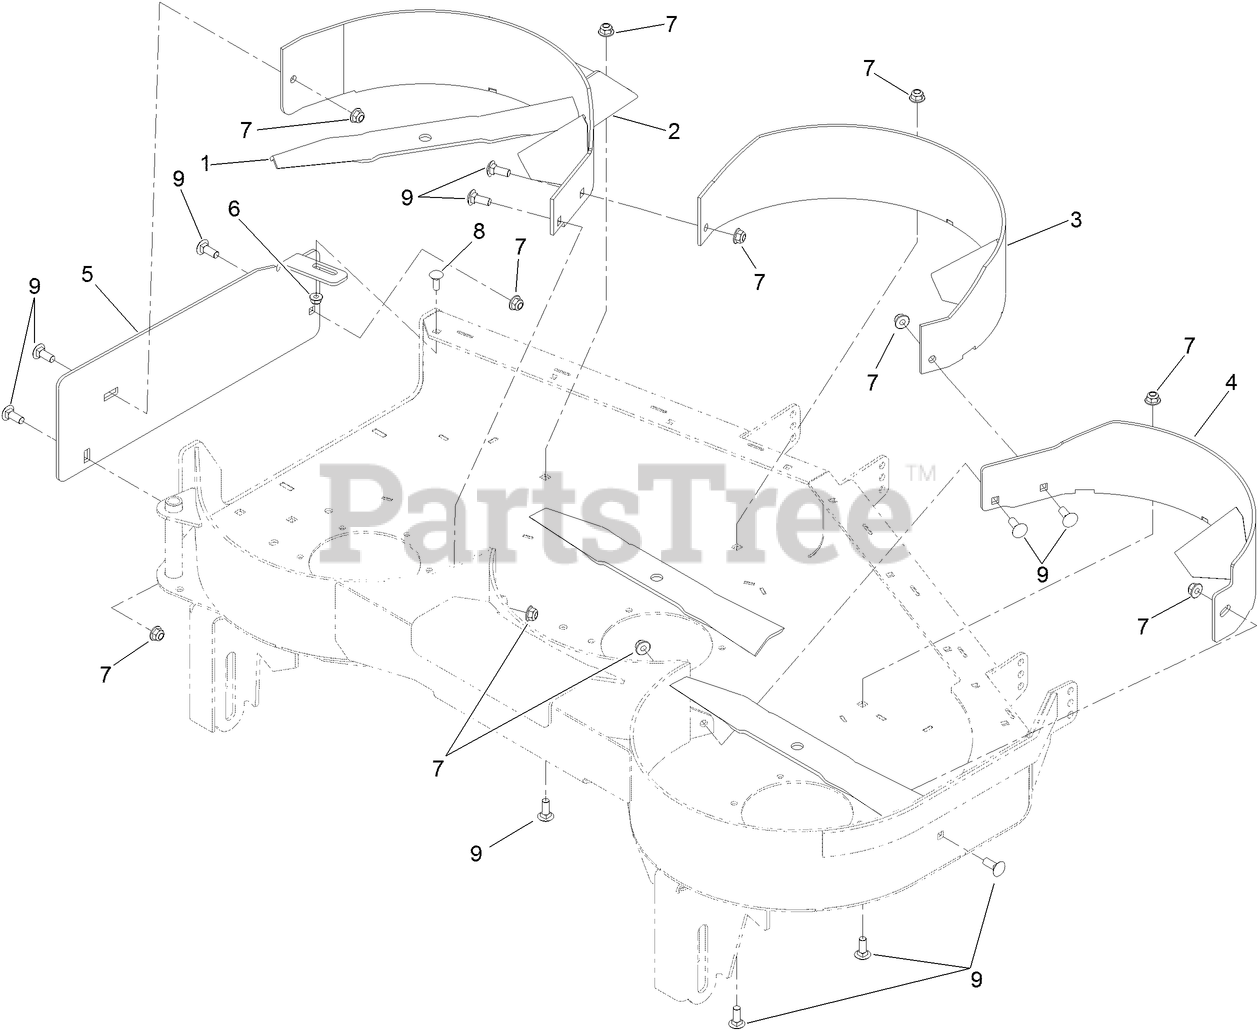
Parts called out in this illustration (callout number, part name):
1	BLADE-MULCH, 16.50 INCH
2	BAFFLE-RH
3	BAFFLE-CENTER
4	BAFFLE-LH
5	PLATE-COVER, DISCHARGE
6	NUT-HF, NI
7	NUT-HF, NI
8	SCREW-CARR
9	BOLT-CARR
